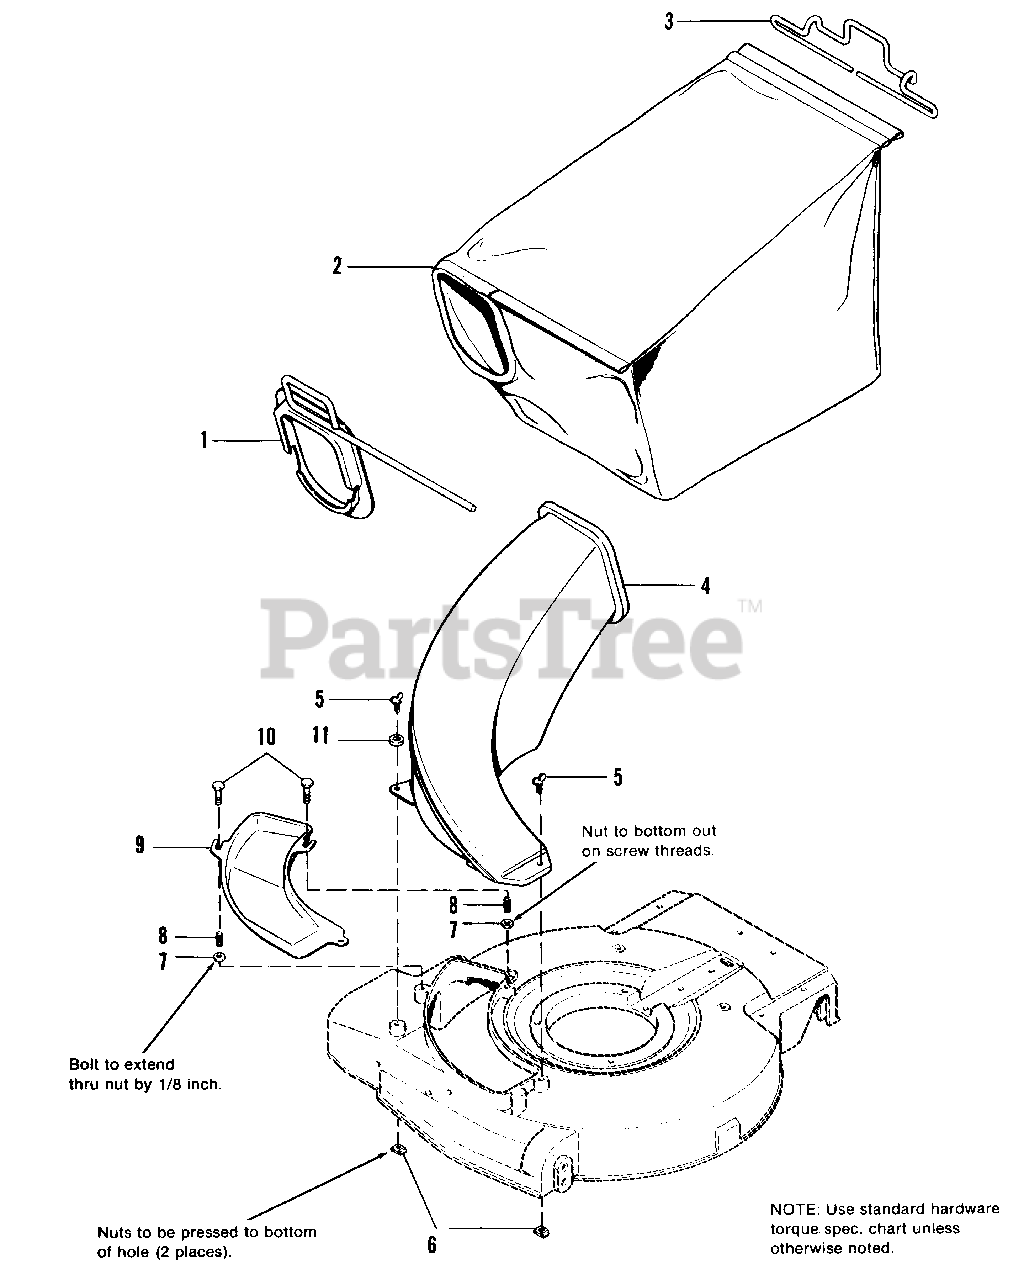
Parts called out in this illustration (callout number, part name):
1	COLLAR ASSY.
2	BAG, Grass
3	SUPPORT, Bag Rear
4	CHUTE ASSY., Grass (use on 1690795)
4	CHUTE ASSY., Grass (use on 1691100)
5	SCREW, Hex Head, 1/4-20 x 5/8
6	NUT, Tinnerman, 1/4-20
7	LOCKNUT, Hex 1/4-20
9	PLATE, Cover
10	SCREW, 1/4-20 x 1
11	WASHER, Plain, 1/4
